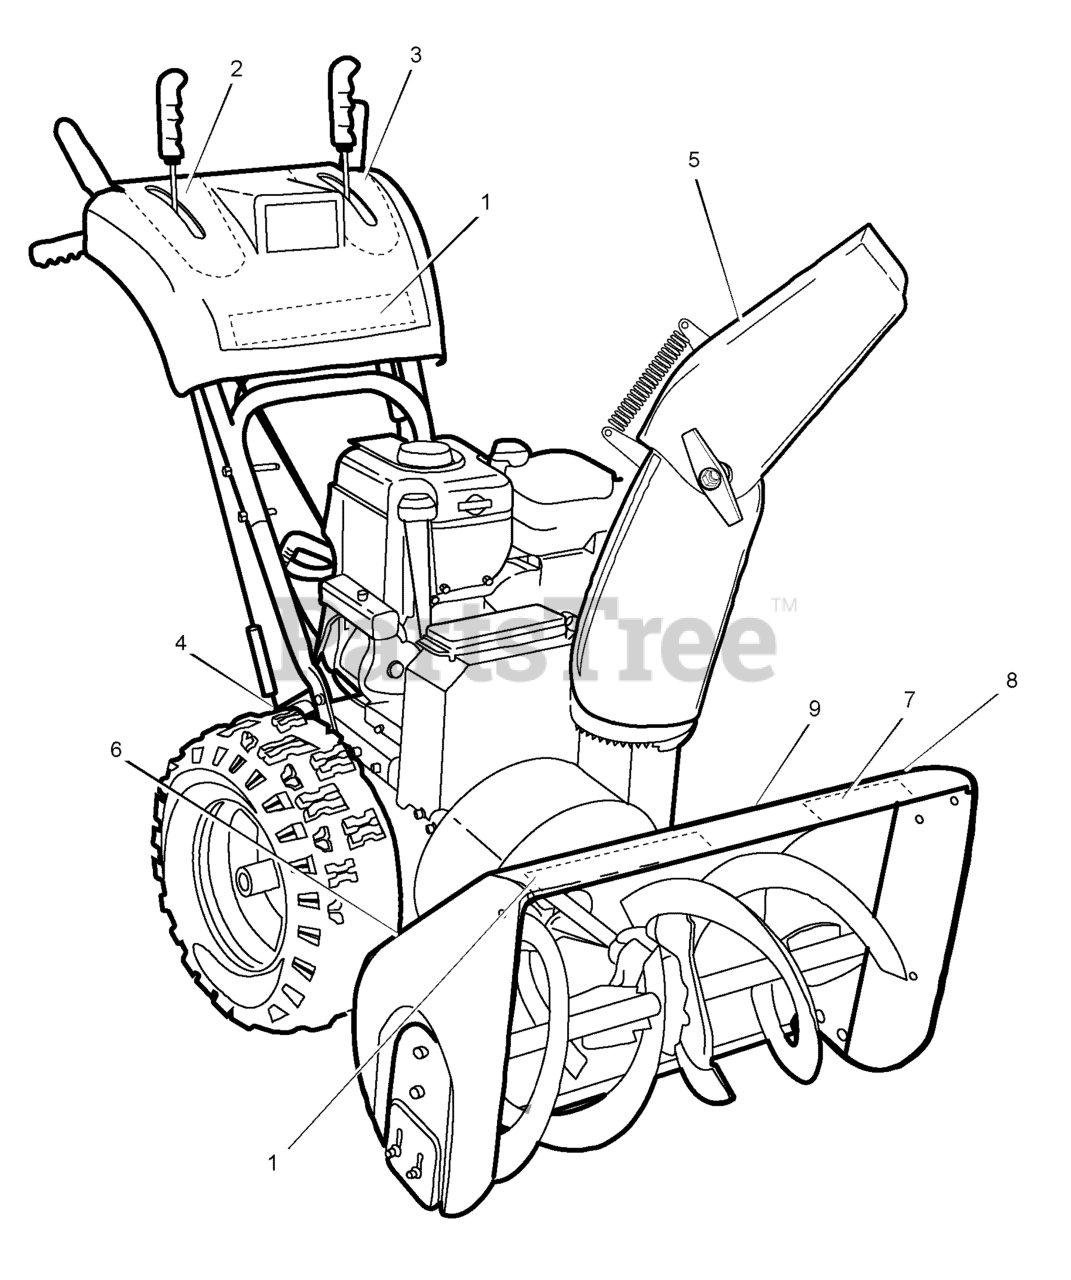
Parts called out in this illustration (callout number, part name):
1	DECAL, CANADIANA
2	DECAL, CANADIANA 1150/69 SPEED
3	DECAL, P5 NON REMOTE
4	DECAL, ID PLATE
5	DECAL, ISO CHUTE CE
6	DECAL, ISO AUGER CE
7	DECAL, FACE HEAD PHONES
8	DECAL, STIGA RH & LH AUGER
9	DECAL, 104db CE
